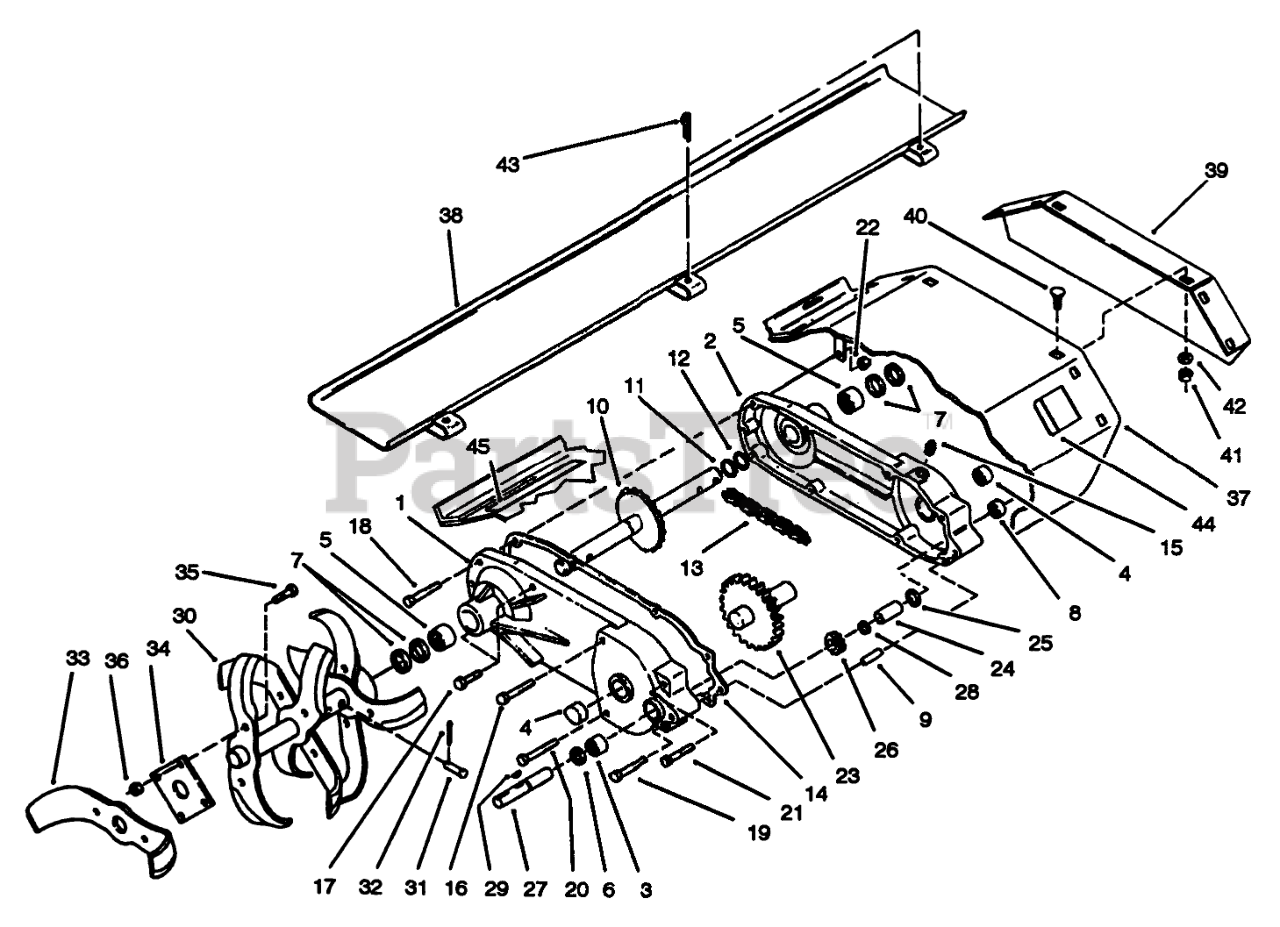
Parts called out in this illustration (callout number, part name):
1	Case
2	Case
3	BEARING-NEEDLE
4	BEARING-NEEDLE
5	BEARING-NEEDLE
6	SEAL-OIL
8	BEARING-NEEDLE
9	PIN-ROLL
10	TINE SHAFT ASM
11	RING-RETAINING
12	WASHER
13	CHAIN
14	GASKET-TRANSMISSION
15	PLUG-PIPE, SQH
16	SCREW-HH
17	SCREW-HH
18	SCREW-HH
19	SCREW-HH
20	SCREW-HH
21	SCREW-HH
22	NUT-LOCK, NI
23	GEAR AND SHAFT ASM
24	TUBE-SPACER
25	WASHER-THRUST
26	GEAR-PINION
27	SHAFT-INPUT
28	Ring-Snap
29	KEY-WOODRUFF
30	Tine R.H.
31	PIN-CLEVIS
32	PIN-COTTER
33	R.H. Tine
34	Plate-Tine Mounting
35	SCREW-HH
36	NUT-LOCK, NI
37	Shield-Tine (Incl. ref. #44)
38	Rear Shield
39	Cover-End
40	CARRIAGE BOLT -4
41	NUT-LOCK, NI
42	WASHER-PLAIN
43	PIN-COTTER
44	DECAL-DANGER
45	DECAL - REAR FRAME
